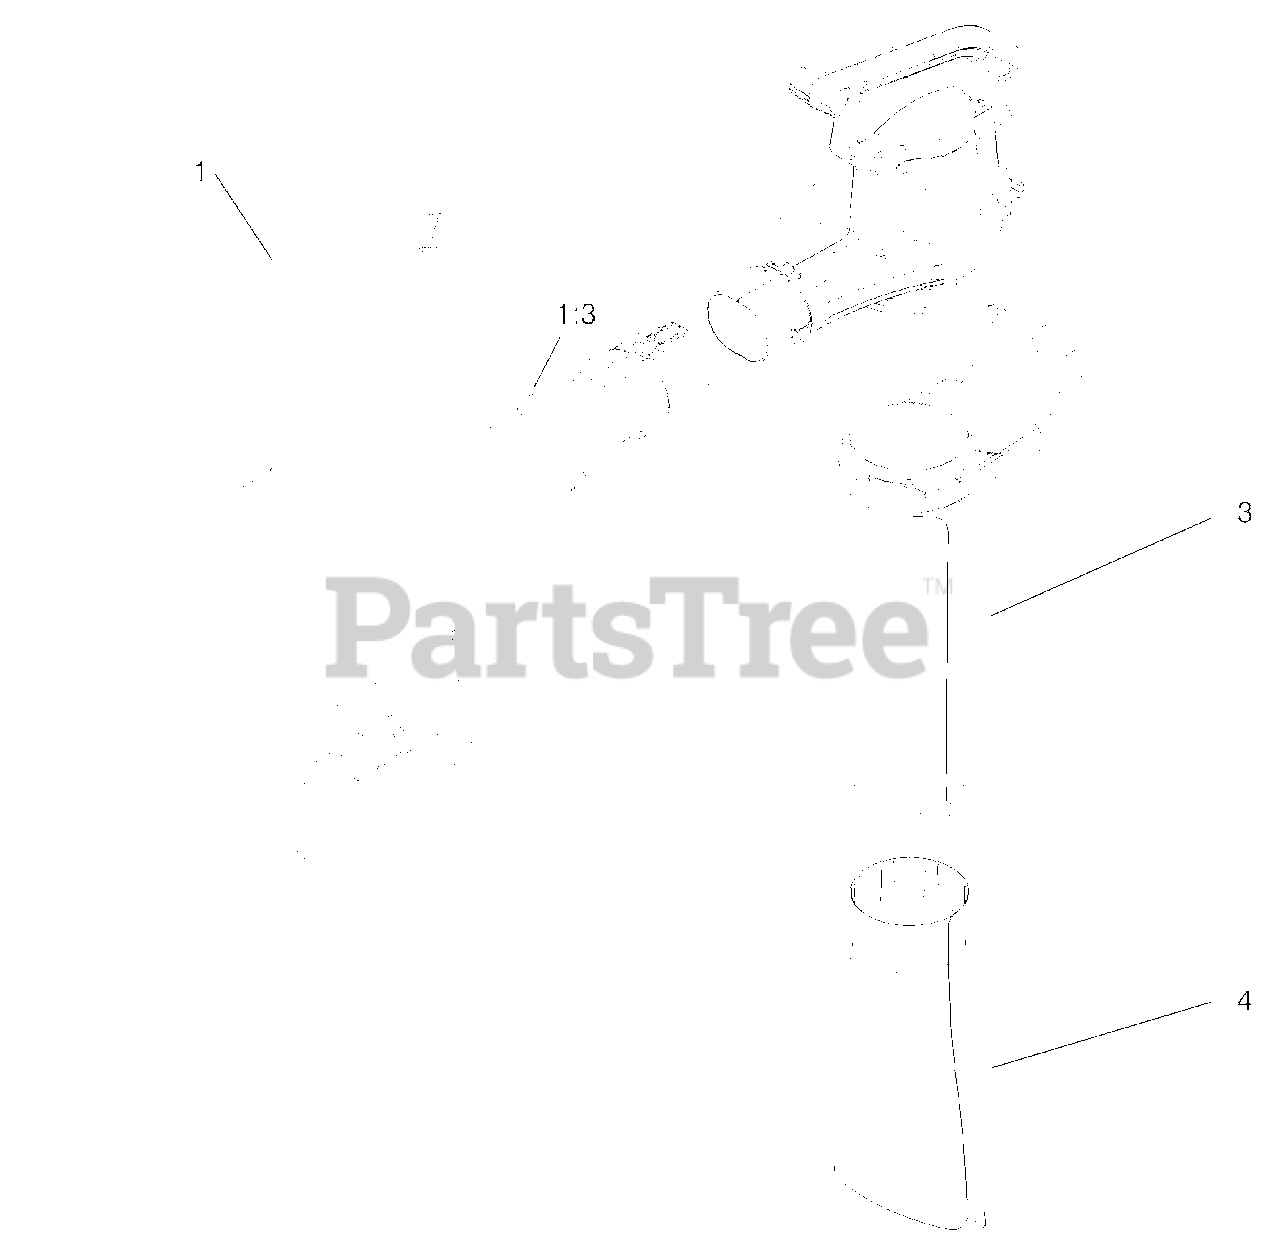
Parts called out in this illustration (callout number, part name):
1:3	Tie-Cable
3	Tube-Vac, Upper
4	Tube-Vac, Lower
